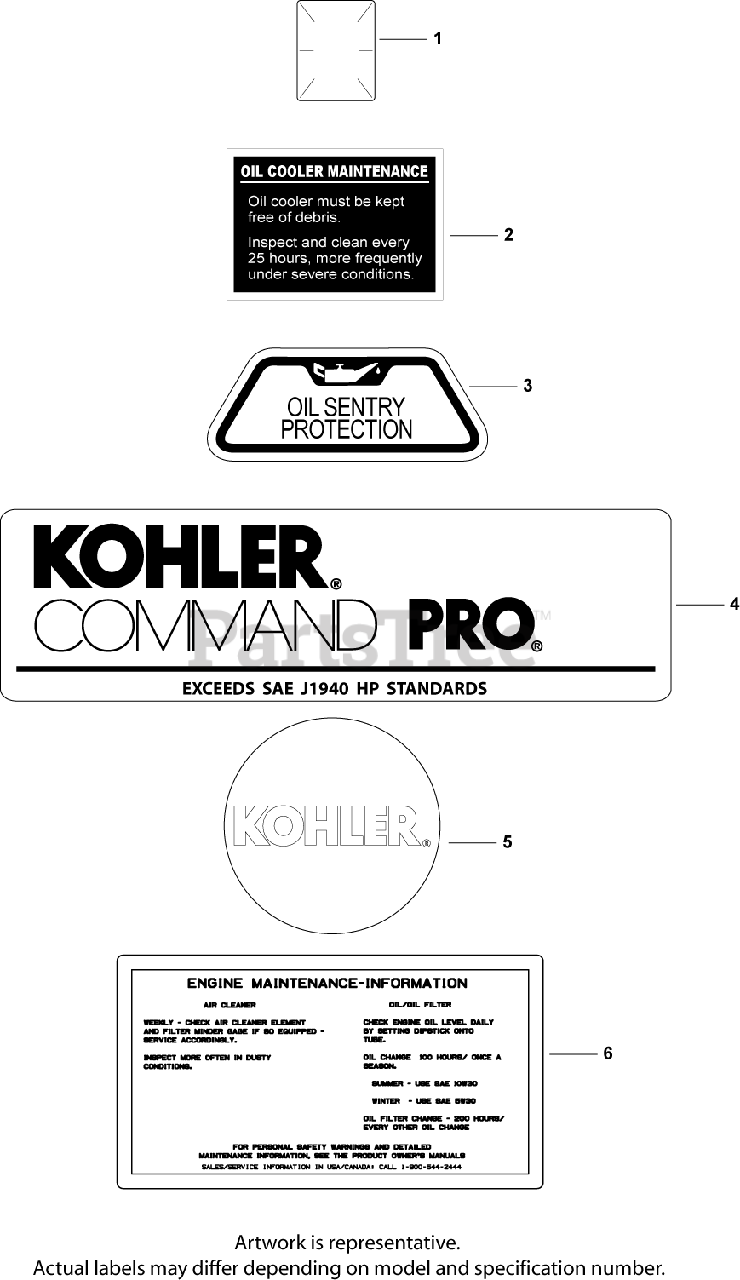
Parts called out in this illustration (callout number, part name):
1	DECAL, CLEAR LAMINATE USE 25 113 70-S
2	DECAL, OIL COOLER - (#DSC)
3	DECAL, OIL SENTRY - (#DSC)
4	DECAL, 22 HP
5	LABEL, (ROUND KOHLER GOLD)-USE 24 113 18
6	DECAL, AIR CLEANER - (#DSC)
